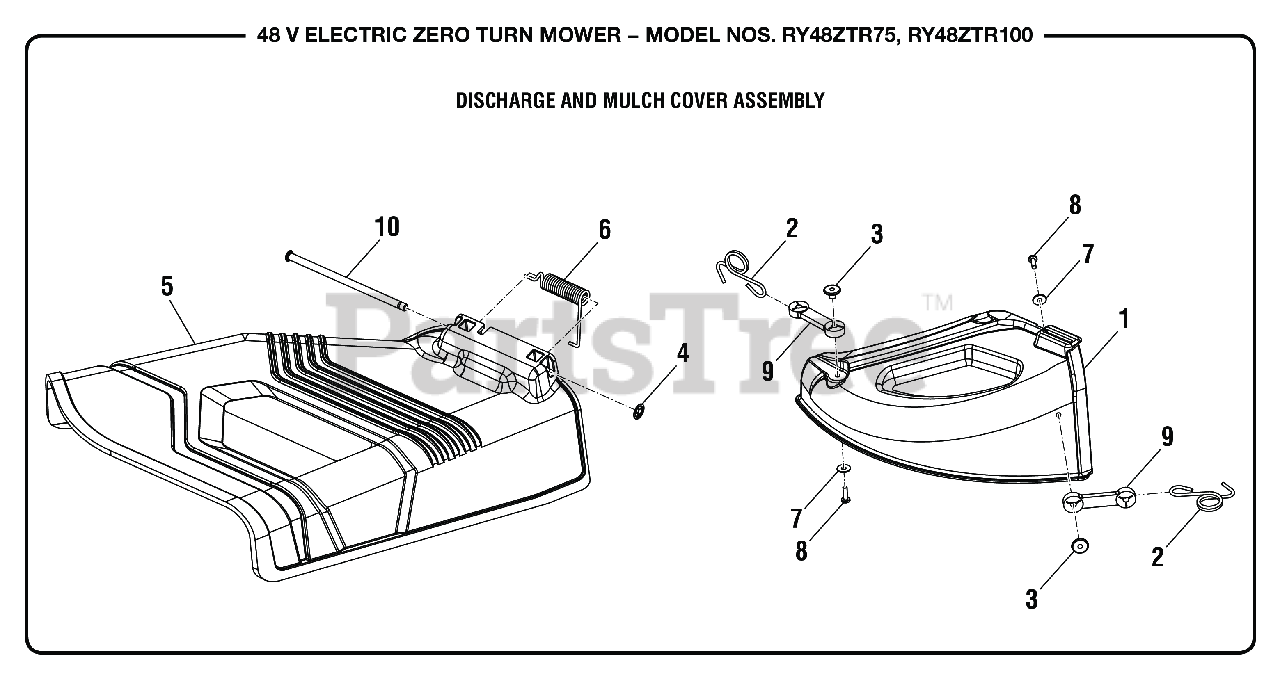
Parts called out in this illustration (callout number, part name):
1	Mulch Plug, ZTR
2	SPRING, LATCH
3	ANCHOR, BUNGIE, RIDING MOWER
4	Retainer Clip
5	Side Discharge Chute, 42 in. Deck
6	Torsion Spring (19 x 62 x 3.02t)
7	WASHER, FLAT, 5.3 X 15 X 1, STEEL,
8	SCREW,PPHMS, M5 X 0.8 X 16 - STEEL,
9	RUBBER STRAP, MULCHING COVER
10	Hinge Pin (7.85 x 175.85)
